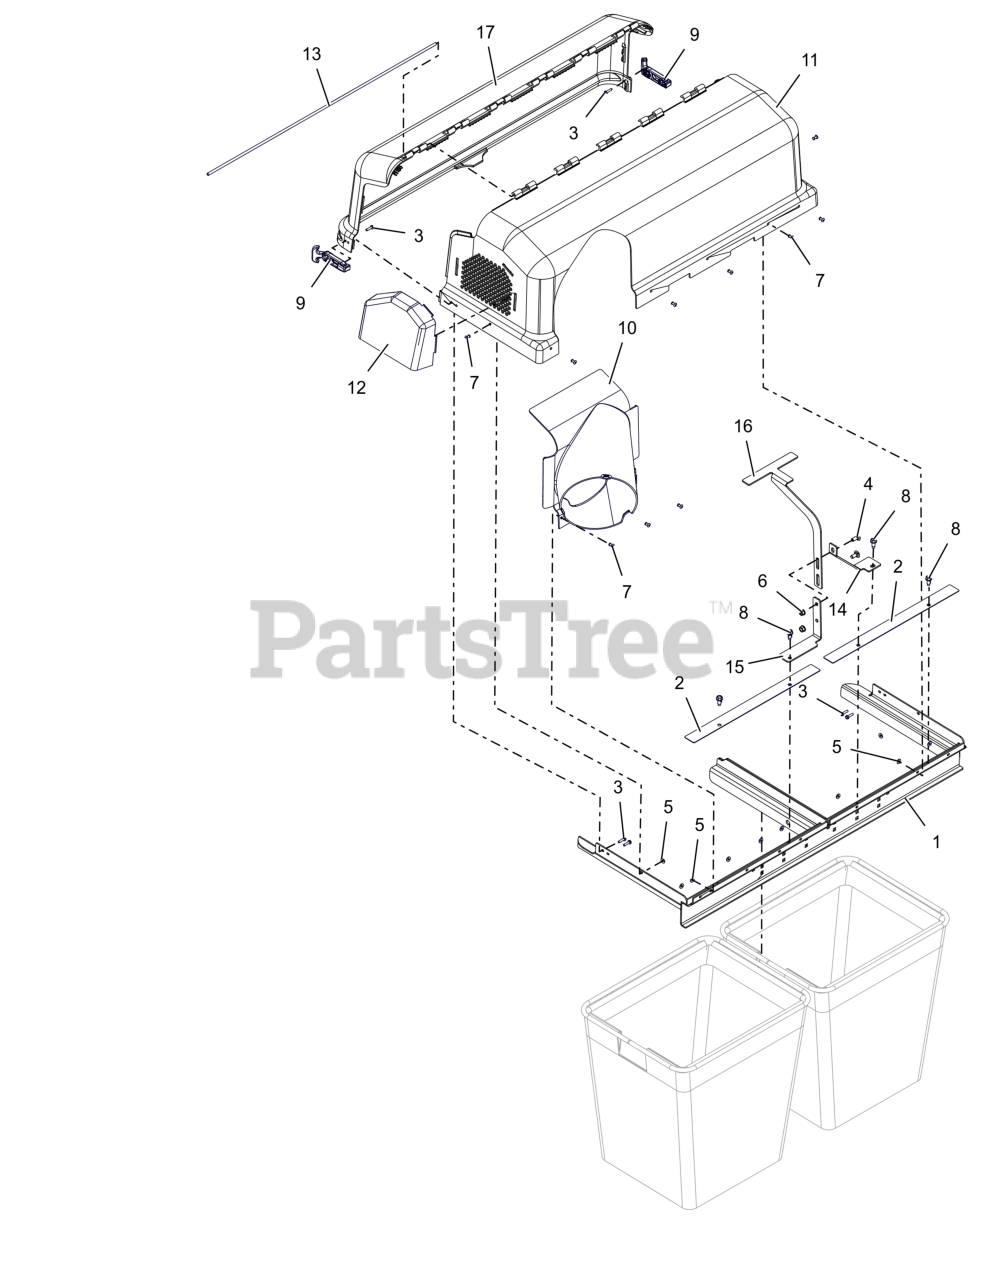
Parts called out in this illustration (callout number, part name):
1	WLDMT, BAGGER FRAME (BLACK)
2	BRKT-BAGGER OVERLAP
3	BLT, HWH #10-24X.75 ZCC
4	BLT,RHSN .31-18X.75 G5 ZCC
5	WSHR-FL-STL .196X.50X.06 ZC120
6	NUT,LK-CTR-FLG .31-18 GF ZCC
7	RIVET, #66 STEEL POP PD BLACK
8	SCR,TAP .312-18X.75 HWH TR ZCC
9	LATCH, RUBBER
10	INTAKE REAR, BAGGER
11	HOOD, REAR BAGGER
12	HOOD, VENT BAGGER
13	ROD, HINGE .25" X 32.5"
14	BRKT, SUPPORT ARM (BLACK)
15	BRKT, BAGGER TOP (BLACK)
16	RIB, BRKT BAGGER (BLACK)
17	KIT- BAGGER DOOR W/DECAL
